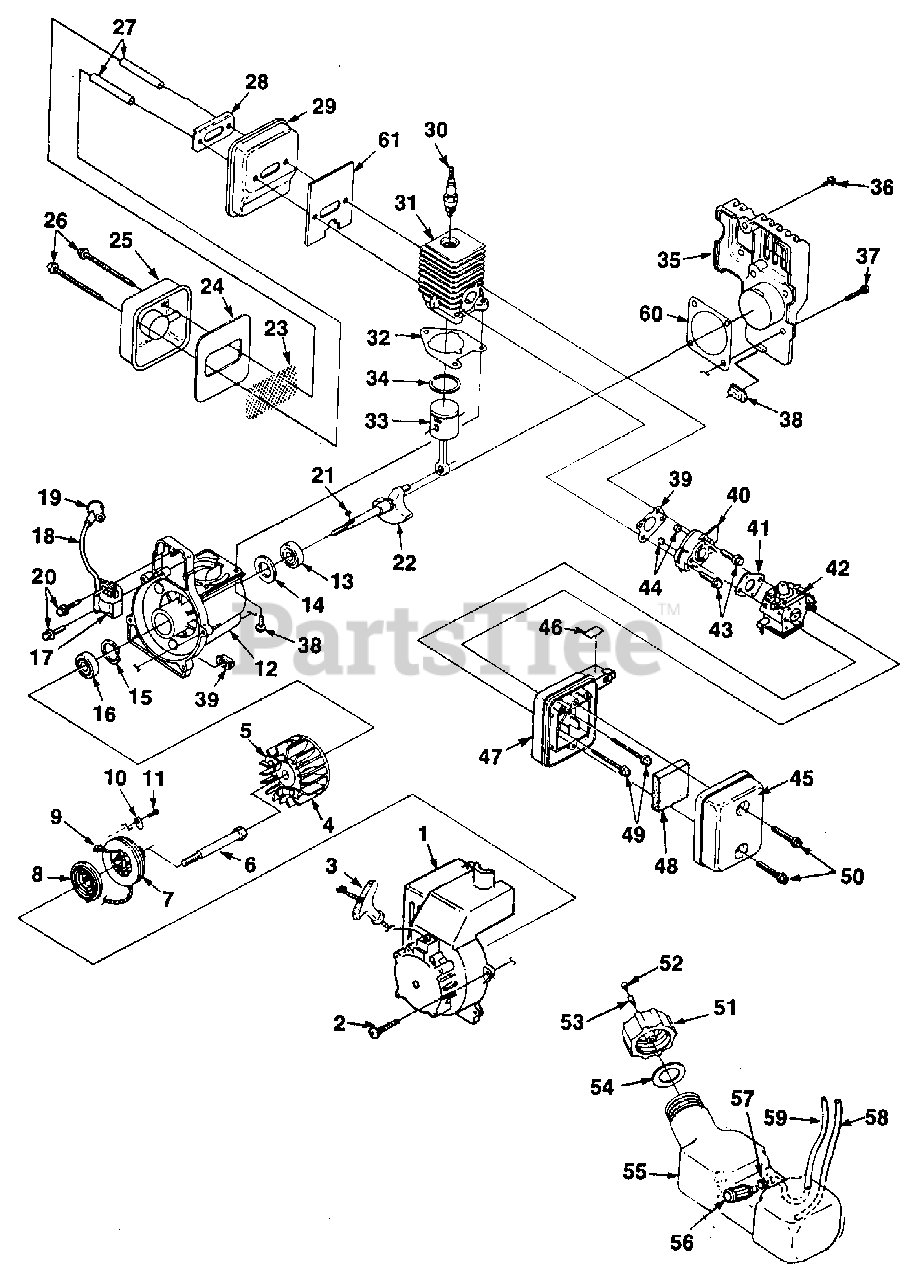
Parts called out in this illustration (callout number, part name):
1	ENGINE HOUSING & DECAL KIT
2	SCREW- (10-24 x 1")
3	GRIP- Starter
4	ROTOR
5	STARTER PAWL KIT
6	EXTENSION SHAFT
7	PULLEY- Starter
8	SPRING & CONTAINER
9	ROPE- Starter
10	BRACKET- Retaining
11	SCREW- Plastite (10 x 1/2")
12	CRANKCASE ASSY.
13	BALL BEARING
15	RING- Retaining
16	BALL BEARING
17	MODULE- Ignition
18	LEAD- Hi tension
19	TERMINAL- Hi tension
20	SCREW- Taptite (8-32 x 1")
21	KEY- Woodruff
22	CRANKSHAFT
23	SCREEN- Spark
24	BAFFLE- Muffler
25	MUFFLER- Cover
26	SCREW- Sems hex hd.
27	SPACER- Muffler
28	PLATE- Reinforcing
29	MUFFLER BODY
30	SPARK PLUG (Champion DJ7Y)
31	CYLINDER
32	GASKET- Cylinder
33	PISTON & ROD ASSY.
34	PISTON RING (Primary Source)
35	COVER- Crankcase
36	SCREW- Taptite (10 x 1/2")
37	SCREW- Taptite (10-24 x 3/4")
38	BUMPER- Rubber
39	HEAT DAM GASKET
40	HEAT DAM
41	CARBURETOR GASKET
42	CARBURETOR (Zama)
43	SCREW- Taptite (10-24 x 1")
44	NUT (10-24)
45	AIR FILTER BOX & COVER
46	DECAL- Choke
47	AIR FILTER BOX
48	AIR FILTER
49	SCREW- Taptite (10-24 x 2 1/4")
50	SCREW- Plastite (8 x 3/4")
51	FUEL CAP ASSY.
52	CAP- Filter
53	VALVE- Filter
54	GASKET- Fuel cap
55	FUEL TANK ASSY.
56	FILTER- Fuel
57	CLAMP- Wire
58	TUBING- Rubber
59	TUBING- Rubber (6.25")
60	GASKET- Crankcase
61	GASKET- Muffler
